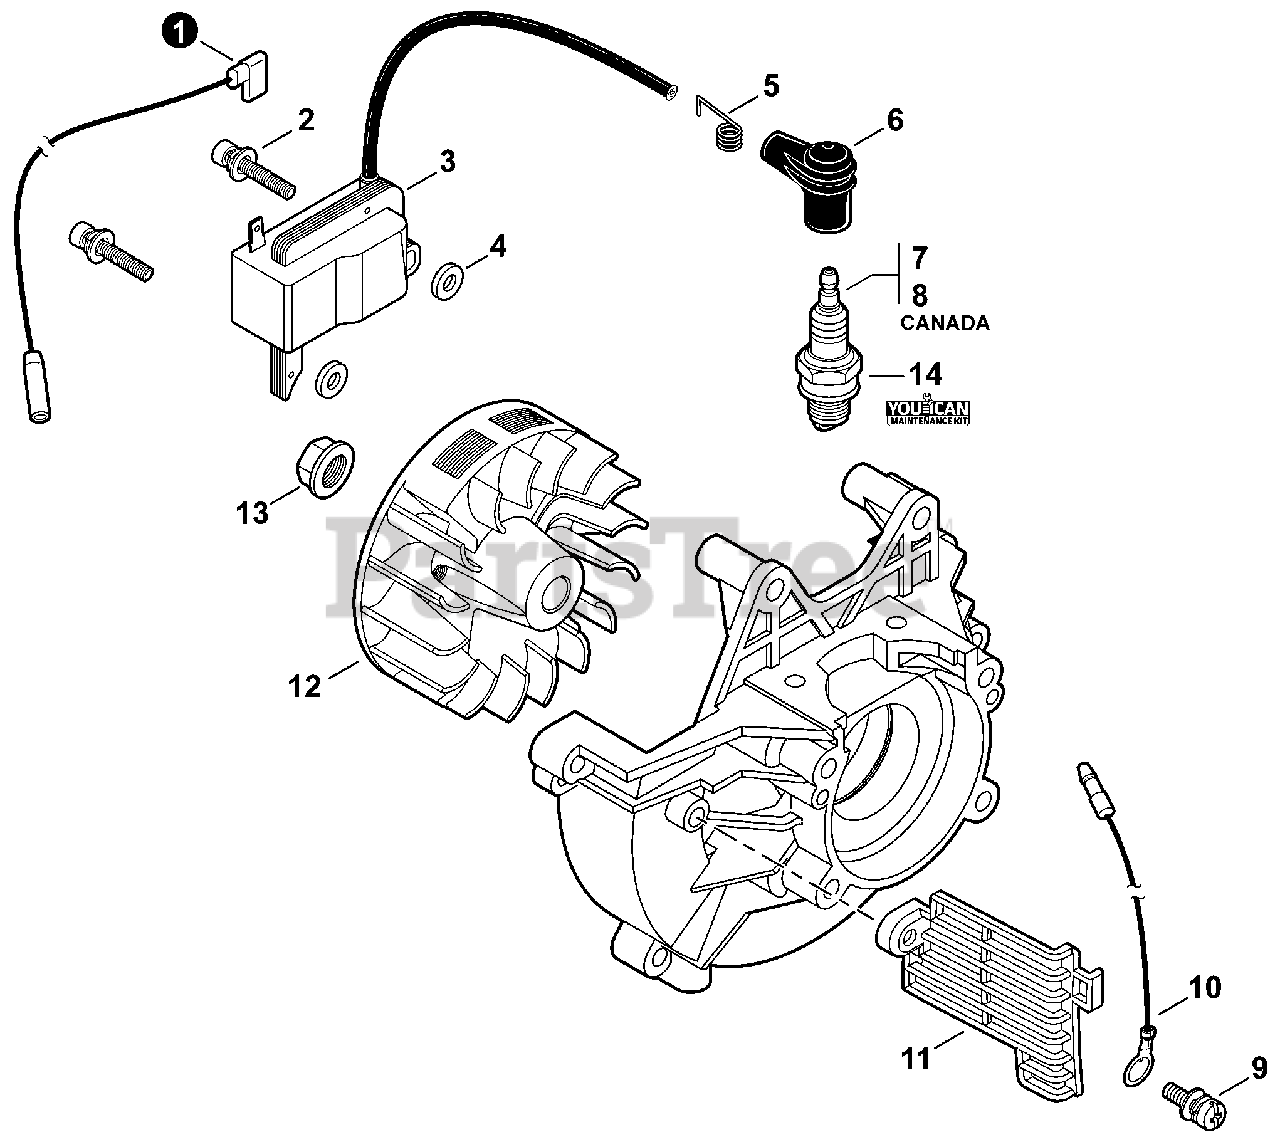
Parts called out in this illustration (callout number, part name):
1	LEAD - IGNITION
2	BOLT 5×20
3	COIL, IGNITION
4	SPACER 5
5	TERMINAL, SPARK PLUG
6	CAP, SPARK PLUG
7	SPARK PLUG - BPM8Y
8	SPARK PLUG - BPMR8Y
9	SCREW 5×10
10	LEAD - GROUND
11	SHIELD, DEBRIS
12	FLYWHEEL
13	NUT, FLANGE M8
14	TUNE-UP KIT - YOUCANT
